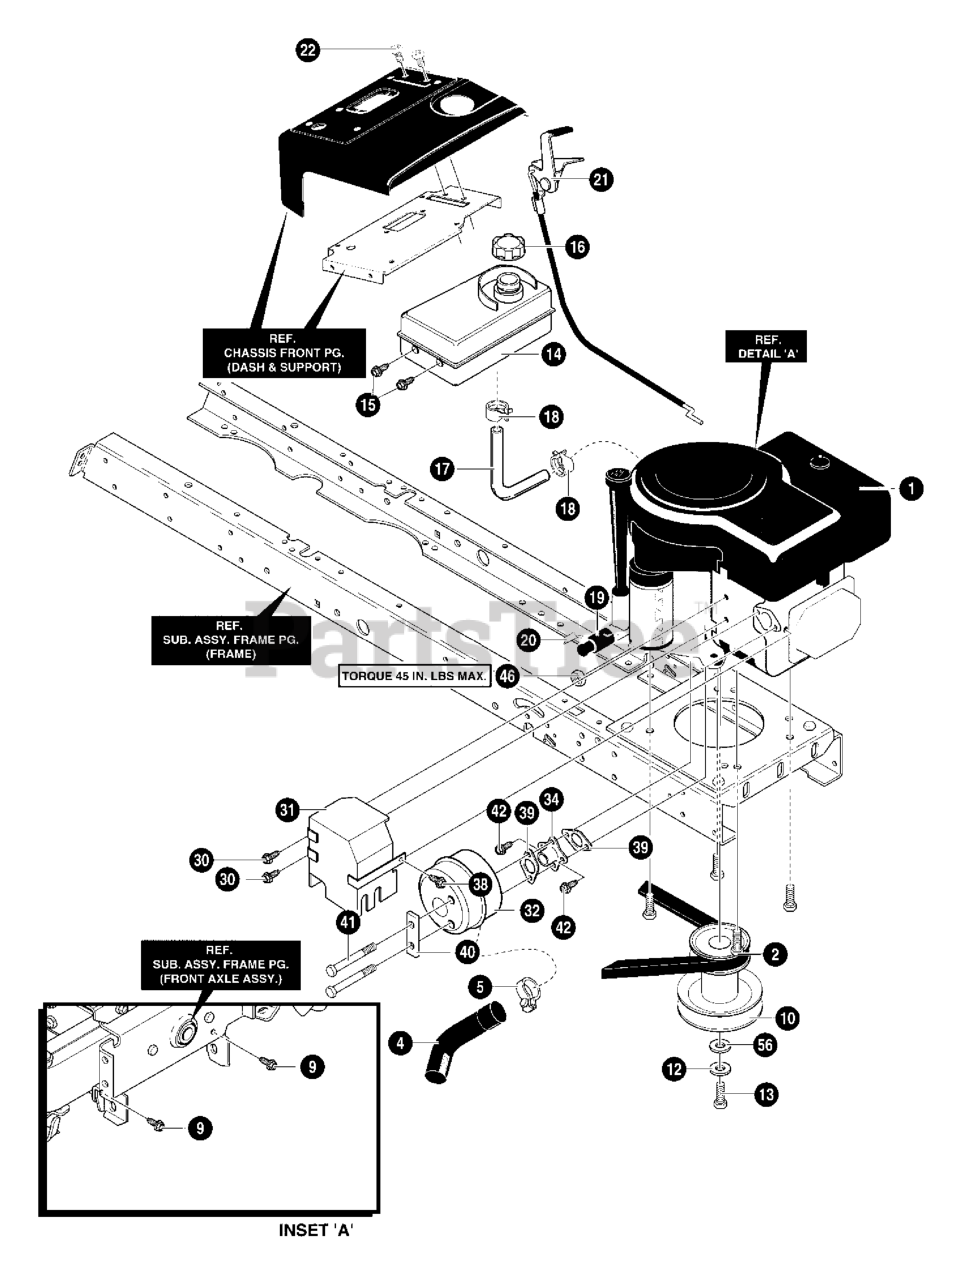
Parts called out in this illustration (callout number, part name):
1	16.5HP INTEK W/O MUF W/EMI
2	SCREW, 3/8-16 x 1.25 WAHHSPTAPP
4	PIPE, EXHAUST
5	CLAMP ASSEMBLY
9	SCREW, 5/16-18 x 0.75 HHC
10	STACK PULLEY ASSY.
12	WASHER, REGSPTLK
13	SCREW, 7/16-20NF1.50
14	TANK, Fuel 1.4 Gal.
15	SCREW, 15TPIX PANHTAP
16	FUEL CAP
17	TUBING, GAS
18	CLAMP, FUEL LINE
19	OIL DRAIN VALVE ASSEMBLY
20	CAP, OIL DRAIN VALVE ASSY
21	THROTTLE CONTROL
22	SCREW, #8-16X.38TRCRTAPABB
30	SCREW, 5/16-18 x 0.625
31	HEAT SHIELD ASSY.
31-1	SHEILD HEAT
31-2	RIVET POP
31-3	BRACKET, HEAT SHIELD RT
31-4	BRACKET, HEAT SHIELD LH
31-5	PLATE, HEAT SHIELD
32	MUFFLER, ROUND
34	MUFFLER ADAPTER
38	SCREW, 1/4-20X.63 HHWATAP
39	GASKET, Exhaust
40	BRACKET, LOCK
41	BOLT, 5/15-18X3.58 HHSH
42	SCREW, 5/16-18 x 0.625
46	NUT, 1/4-20 REGHXJAM
56	WASHER, FLAT .480X1.00
